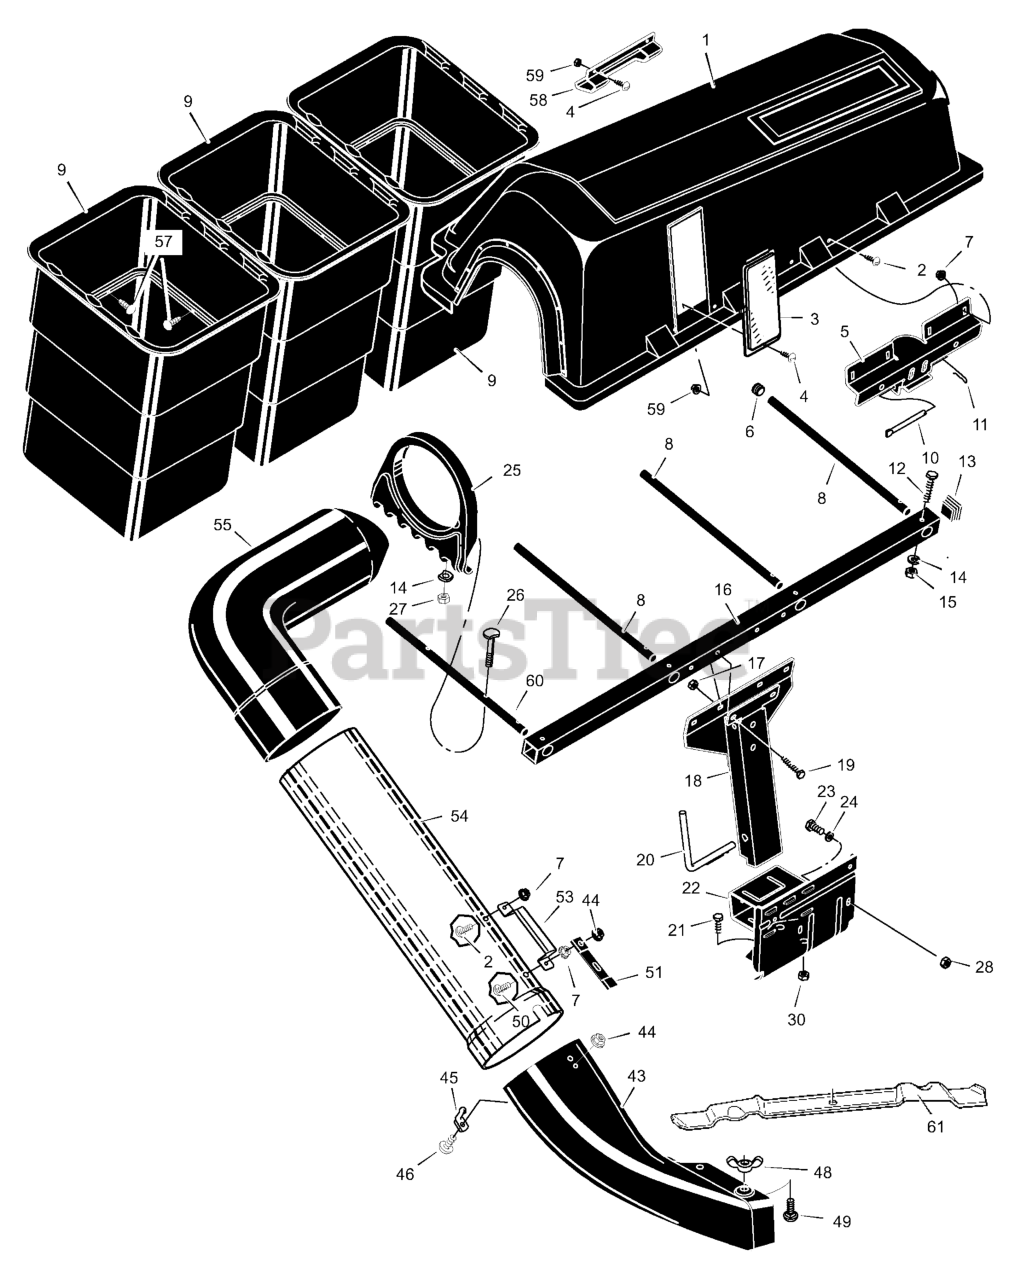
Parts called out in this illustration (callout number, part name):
1	Cover, Bagger
5	Hinge, Bracket
7	Nut, Hex
8	Tube, Container
9	Container
10	Pin, Cover Hinge
11	Pin, Hair
13	Plug
14	Lockwasher
16	Tube, Support
17	Nut
18	Assembly, Channel
20	Pin, Channel Mount
21	Bolt, Hex
22	Assembly, Bagger Mount
23	Bolt, Hex
25	Holder, Elbow
27	Washer
28	Nut, Super Flange
30	Nut, Hex
43	Tube, Extension
44	Locknut, Flange
45	Pin, Latch
46	Bolt, Carriage
48	Wingnut
49	Bolt, Carriage
51	Latch, Rubber
53	HANDLE, Connect Tube
54	Tube, Connecting
57	Fastener, Panel
58	Handle, Plastic
59	Nut, Hex
60	Tube, Right Container
61	Blade, High Lift
